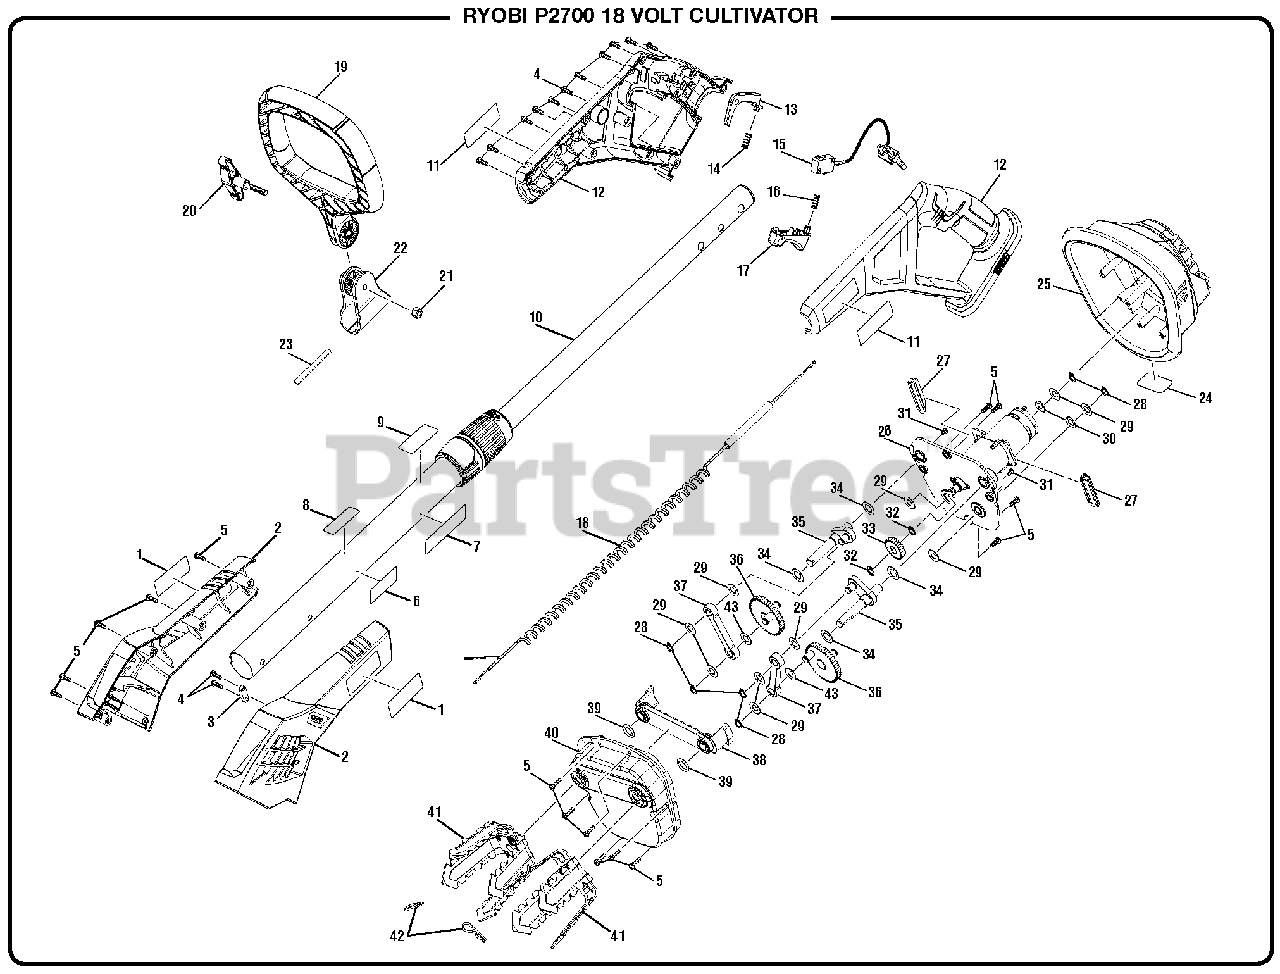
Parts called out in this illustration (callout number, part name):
1	Logo Label (Housing)
2	Housing Assembly
3	Cord Clamp
4	Screw (M3.5 x 14 mm)
5	Screw (M4 x 14 mm, T15 Torx Pan Hd.)
6	Data Label
7	Warning Label (French/Spanish)
8	Lithium-ion Label
9	Warning Icon Label
10	Pole/Telescoping Shaft Assembly
11	Logo Label (Handle)
12	Rear Handle Assembly
13	Lock-Out Button
14	Compression Spring
15	Switch Assembly
16	Compression Spring
17	Switch Trigger
18	Wire Assembly
19	Front Handle Assembly
20	Wing Bolt (M6 x 1 in.)
21	Hex Nut (M6)
22	Clamp Assembly
23	Rubber Plate
24	No Hands Label
25	Lower Housing
26	Motor and Clutch Assembly
27	Rubber Plate
28	C-Ring (Retaining Ring)
30	Wavy Washer
31	Screw (M3 x 8 mm, Pan Hd.)
32	Retaining Ring
33	Clutch Gear
35	Pivot Arm Assembly
36	Drive Gear Assembly
37	Connecting Rod
38	Bracket Assembly
40	Gear Box Cover
41	Tine Assembly
42	Hitch Pin
